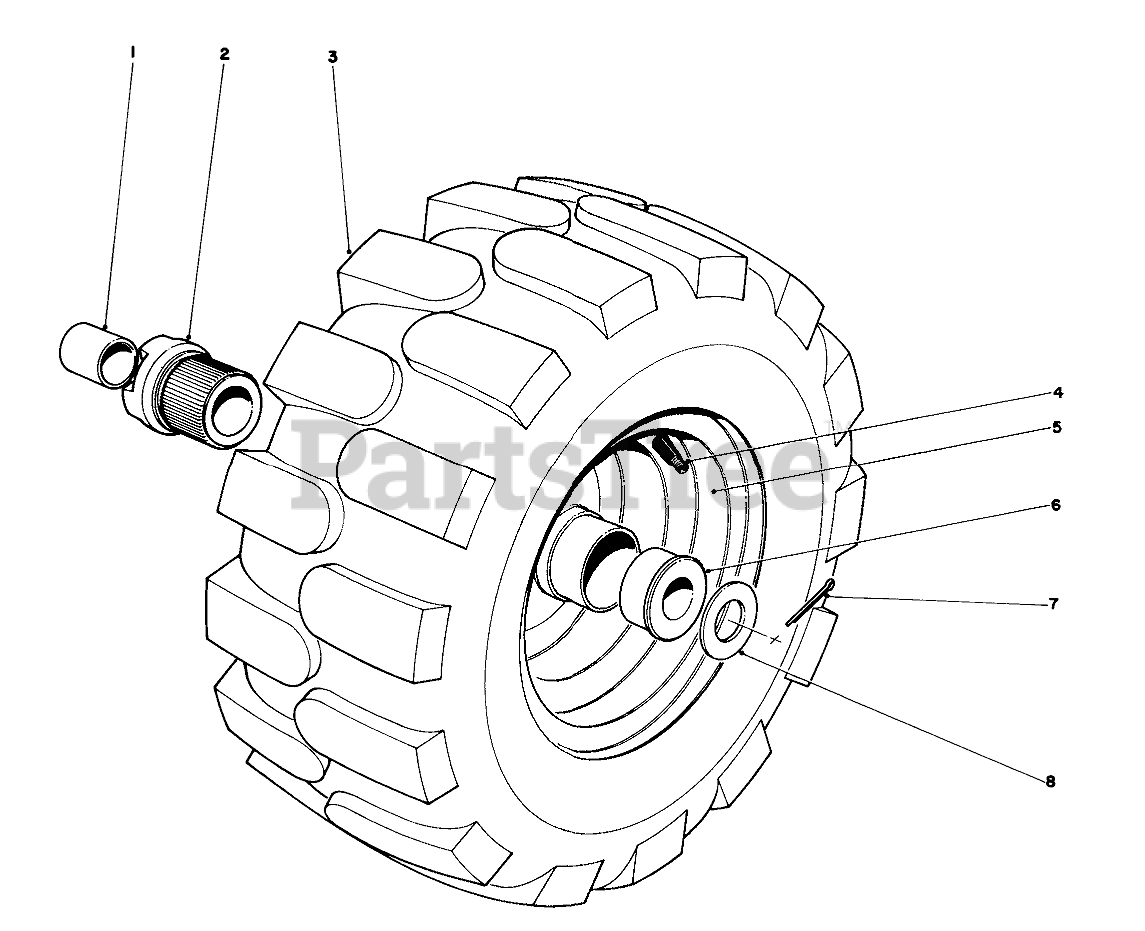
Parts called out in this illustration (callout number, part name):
1	.877ID X .750LG BSHG
2	JAW HUB
4	STEM-VALVE
6	Bushing
7	PIN-COTTER
8	WASHER-THRUST
